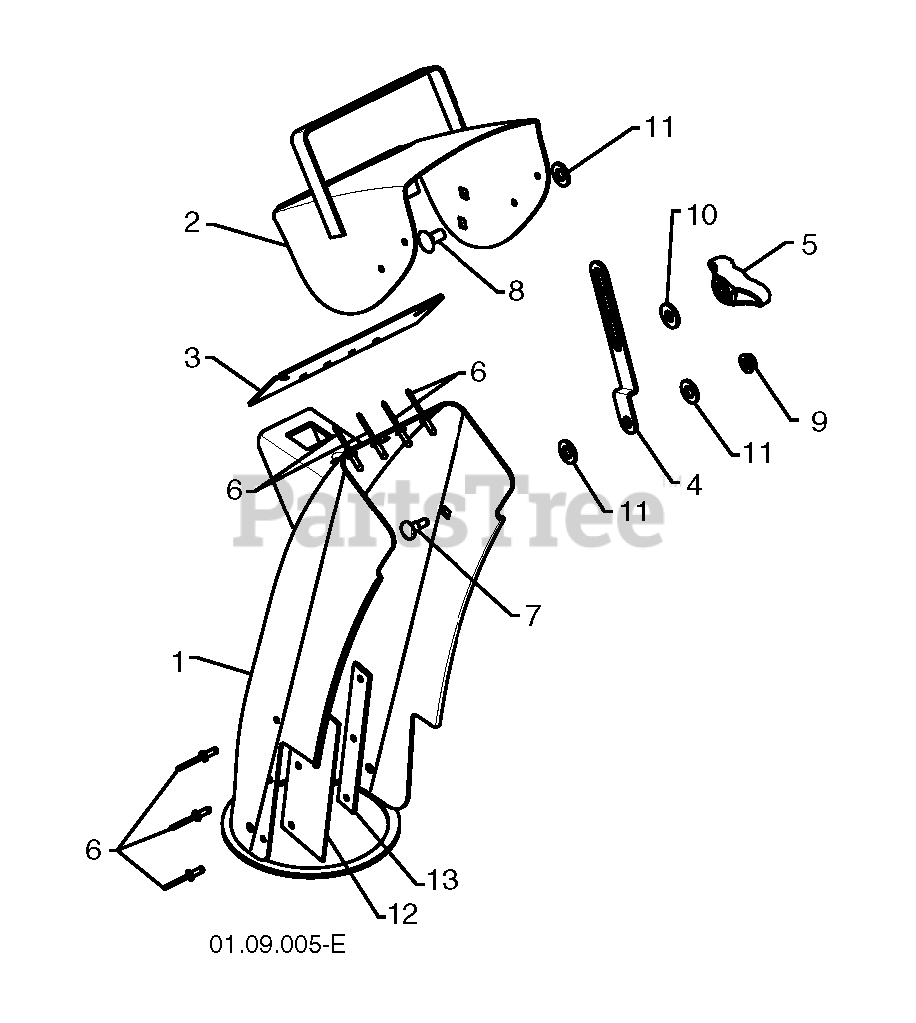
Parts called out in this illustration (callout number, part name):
1	RP CHUTE.WELDMENT.PNT.ORANGE
2	DEFLECTOR.WELDMENT.PNT.ORANGE
3	SEAL.DEFLECTOR
4	STRAP.SLOTTED.SERVICE
5	KNOB LEVER, BLACK
6	RIVET BLIND
7	SHOULDER BOLT
8	BOLT
9	NUT.HEX.FLANGE.1/4
10	WASHER.20X8.5
11	WASHER, NYLON FRICTION
12	SHIELD.SNOW.CHUTE
13	RP STRAP.SHEILD.RETAINER
